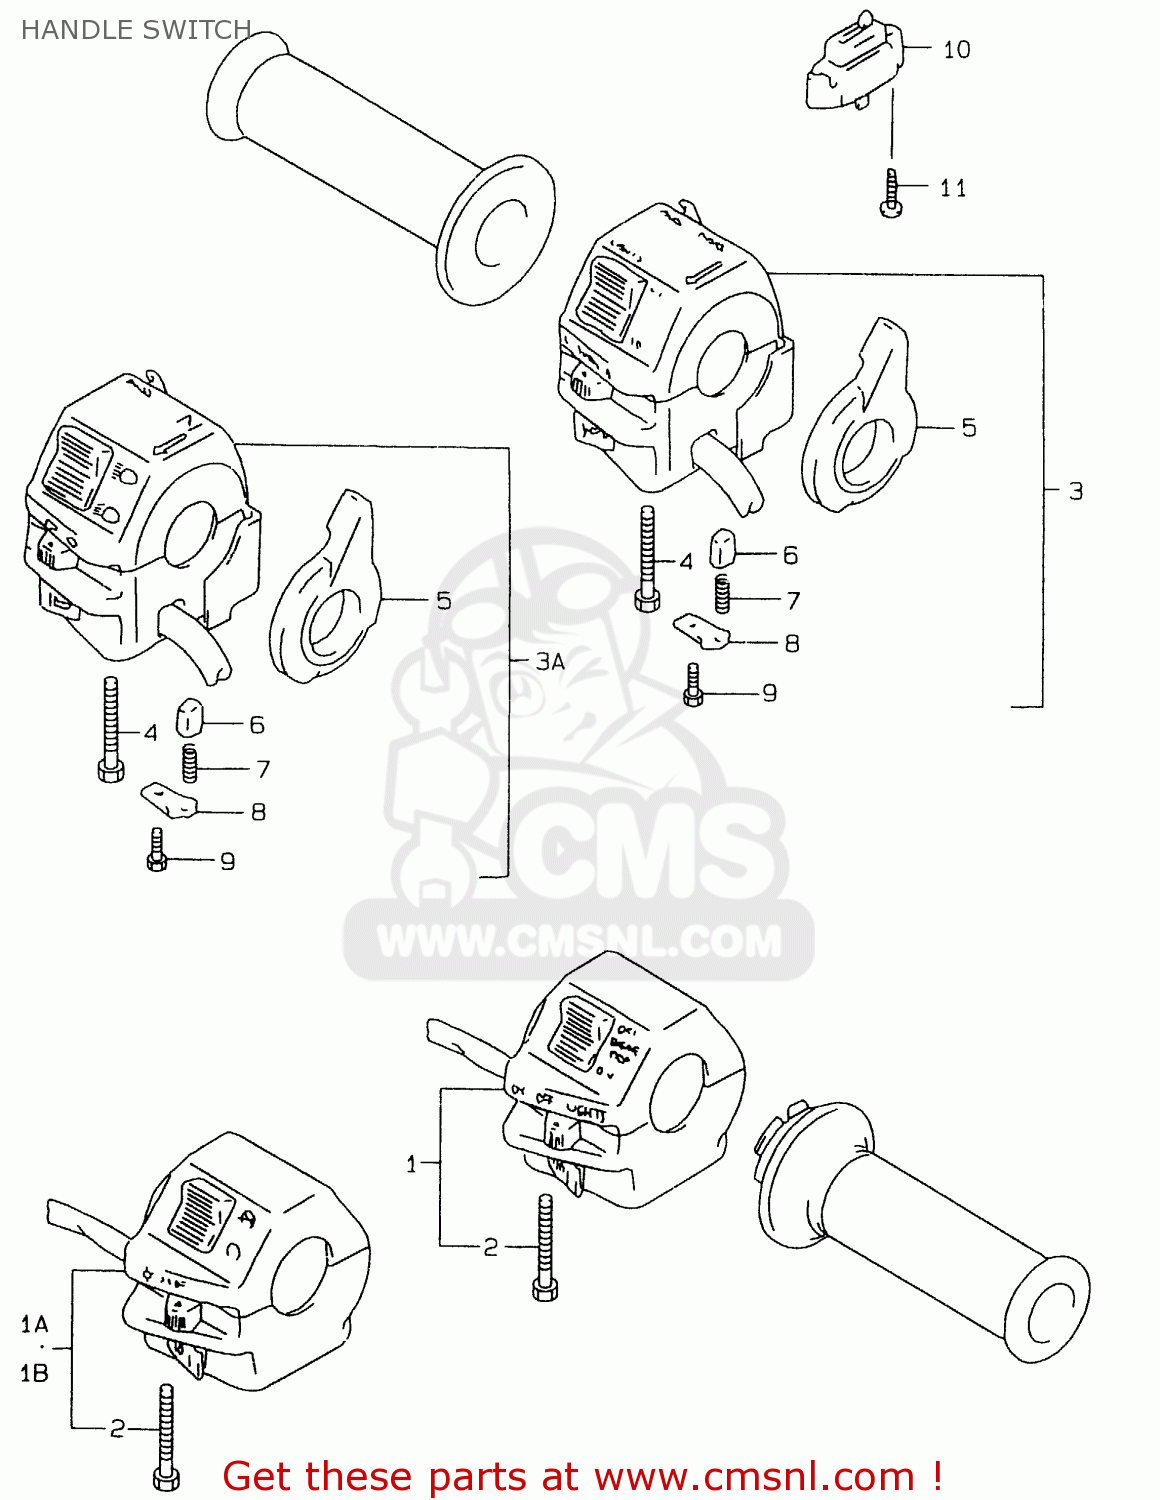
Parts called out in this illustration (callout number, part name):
1	SWITCH,HANDLE,
1A	SWITCH ASSY,HANDLE,R
1B	SWITCH ASSY,HANDLE,R
2	SCREW, 5X45
3	SWITCH,HANDLE
3A	SWITCH ASSY,HANDLE,L
4	SCREW, 5X45
5	LEVER,CHOKE
6	PIECE,SLIDE
7	SPRING
8	PLATE
9	SCREW, TRUNK BOX
10	SWITCH ASSY,CLUTCH
11	SCREW
